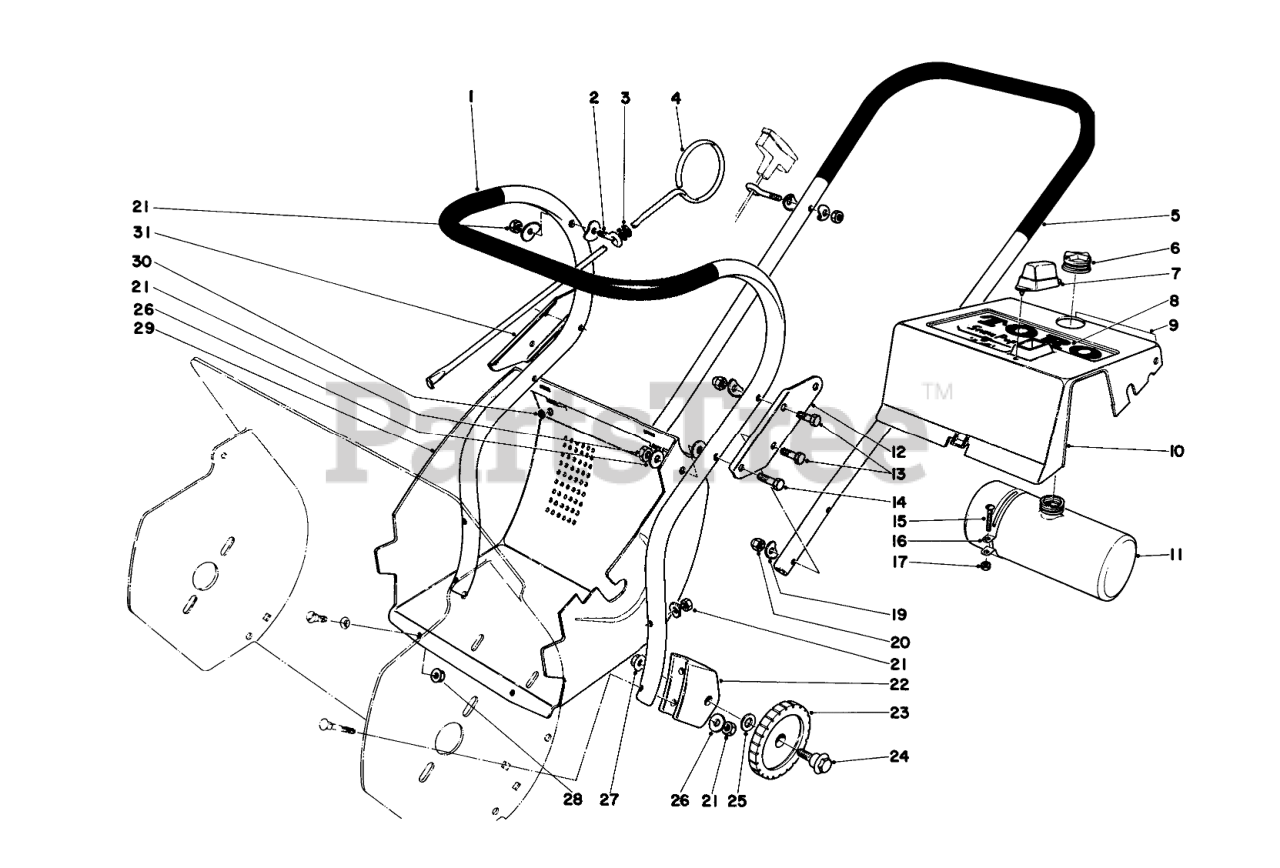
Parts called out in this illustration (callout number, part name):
1	Handle Lower
2	Bolt-Eye
3	GROMMET
4	Vane Adj. Rod
5	Handle Upper
6	Gas Cap
8	Decal
9	Decal
10	Upper Shroud (Incl. Ref. #7)
11	Gas Tank Assembly (Incl. Ref. #6 & 18)
12	SPLICE PLATE
13	Capscrew
14	SCREW-HH
15	10-24 X 1 RND HD MS
16	1/2 GAS TANK CLAMP
17	NUT-SQ
19	WASHER
20	NUT-CAP
21	Nut
22	Bracket Wheel
23	Wheel
24	Bolt-Shoulder
25	WASHER-PLAIN
26	WASHER-FLAT
27	NUT-HHF
28	NUT-LOCK, FLANGE
29	Lower Shroud
30	SNO PUP PLATED EYELET
31	Plate-Splice
